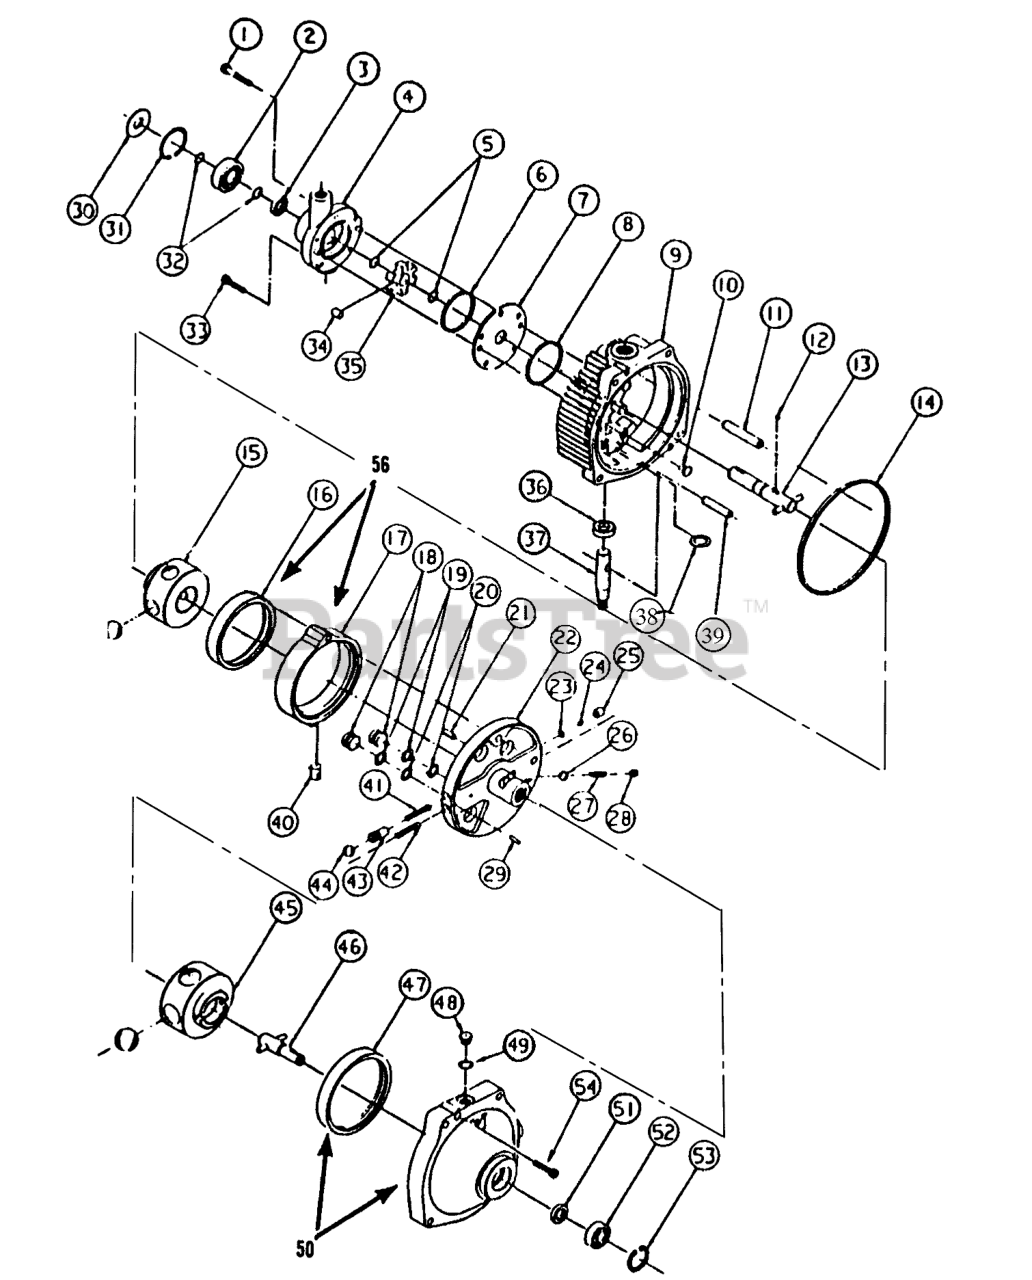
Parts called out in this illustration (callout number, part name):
1	Screw
2	Bearing-Input
3	Seal
4	Housing-Pump Assembly (Incl. Ref. # 2)
5	Ring
6	Ring-Seal
7	Plate
8	Ring-Seal
9	Cover Assembly (Incl. Ref. #3, 6, 8,10,11,19, 20, 36-39,& 51)
10	Button
11	Pin-Pivot
12	Pin
13	Shaft-Input
14	Ring-Seal
15	Rotor-Pump
16	PUMP-RACE
17	Ring-Cam
18	Piston
19	Ring-Back Up
20	"O"Ring
21	Pin-Coil
22	Pintle Assembly (Inc. Ref. #21, 23-29 & 41-44)
23	Ring-Retaining
24	Ball
25	Body-Check Valve
26	Ball
27	Spring-Relief Valve
28	Plug-Relief Valve
29	Pin
30	SHIELD-GRASS
31	RETAINING-RING
32	Ring
33	Screw
34	Roller
35	Carrier
36	Seal
37	Kit-Control
38	Washer
39	Dowel
40	Insert-Cam Ring
41	Spring-Acc. Valve
42	Spring-Acc. Valve
43	Body-Acc. Valve
44	Ball
45	Rotor-Motor
46	Shaft-Output
47	Race-Motor
48	Plug-"O"Ring (incl. Ref. #49)
49	O-Ring
50	Body Assembly (Incl. Ref. #51, 53 & 54)
51	Seal ASM
52	Bearing-Output
53	Retaining Ring
54	Screw
55	Kit-Seal, Overhaul (Incl. Ref.# 3, 6, 8,14,19,20, 36, 49 & 51)
56	Ring-Cam
